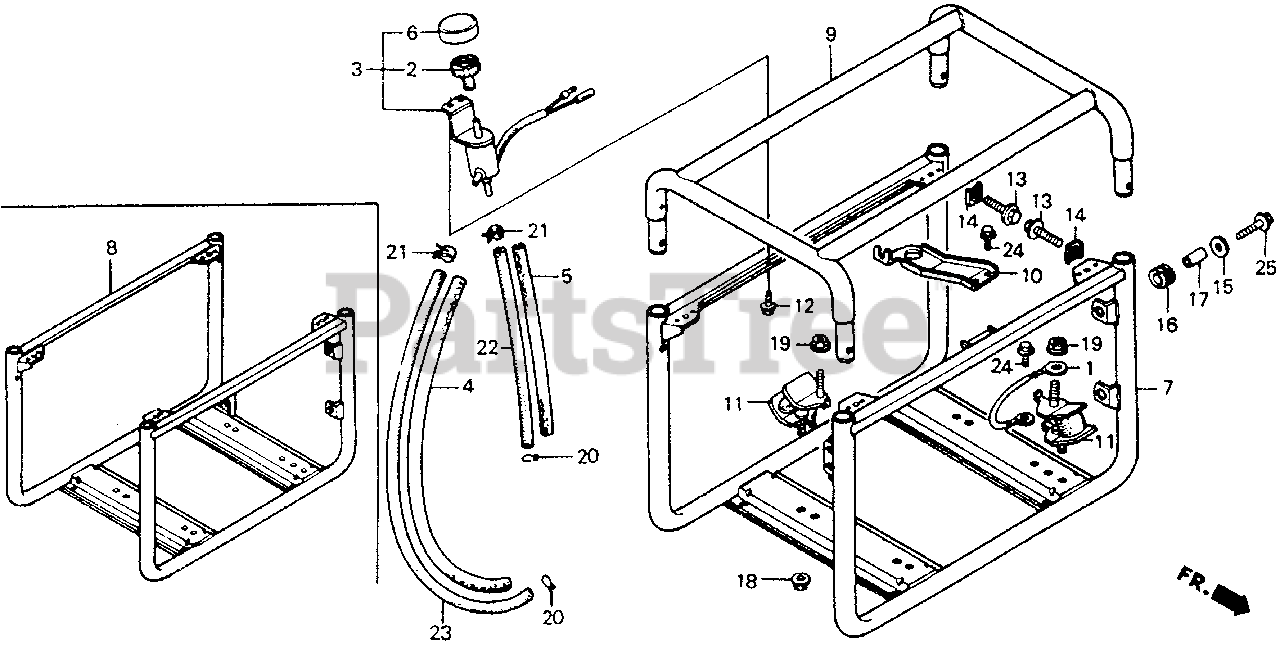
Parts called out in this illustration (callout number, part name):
1	CABLE, GROUND
2	FILTER ASSY., SOLENOID VALVE
3	VALVE ASSY., CONTROL (NOT AVAILABLE)
4	PROTECTOR, TUBE (9X390) (NOT AVAILABLE)
5	PROTECTOR, TUBE (9X130)
6	CAP, AIR FILTER
8	FRAME (LOWER)
9	FRAME (UPPER)
10	STAY, BUMP STOP
11	RUBBER (LOWER)
12	BOLT, FLANGE (5X10)
13	BOLT, FLANGE (8X20)
14	WASHER, FRAME JOINT
15	WASHER, FLAT (20MM)
16	RUBBER, CONTROL BOX
17	COLLAR, CONTROL BOX
18	NUT, FLANGE (8MM)
19	NUT, FLANGE (10MM)
20	CLIP, TUBE (B7)
21	CLIP, TUBE (D8)
22	BULK HOSE, VACUUM (3.5X1000) (3.5X140)
23	BULK HOSE, VACUUM (3.5X1000) (3.5X400)
24	BOLT, FLANGE (6X10)
25	BOLT, FLANGE (6X18)
